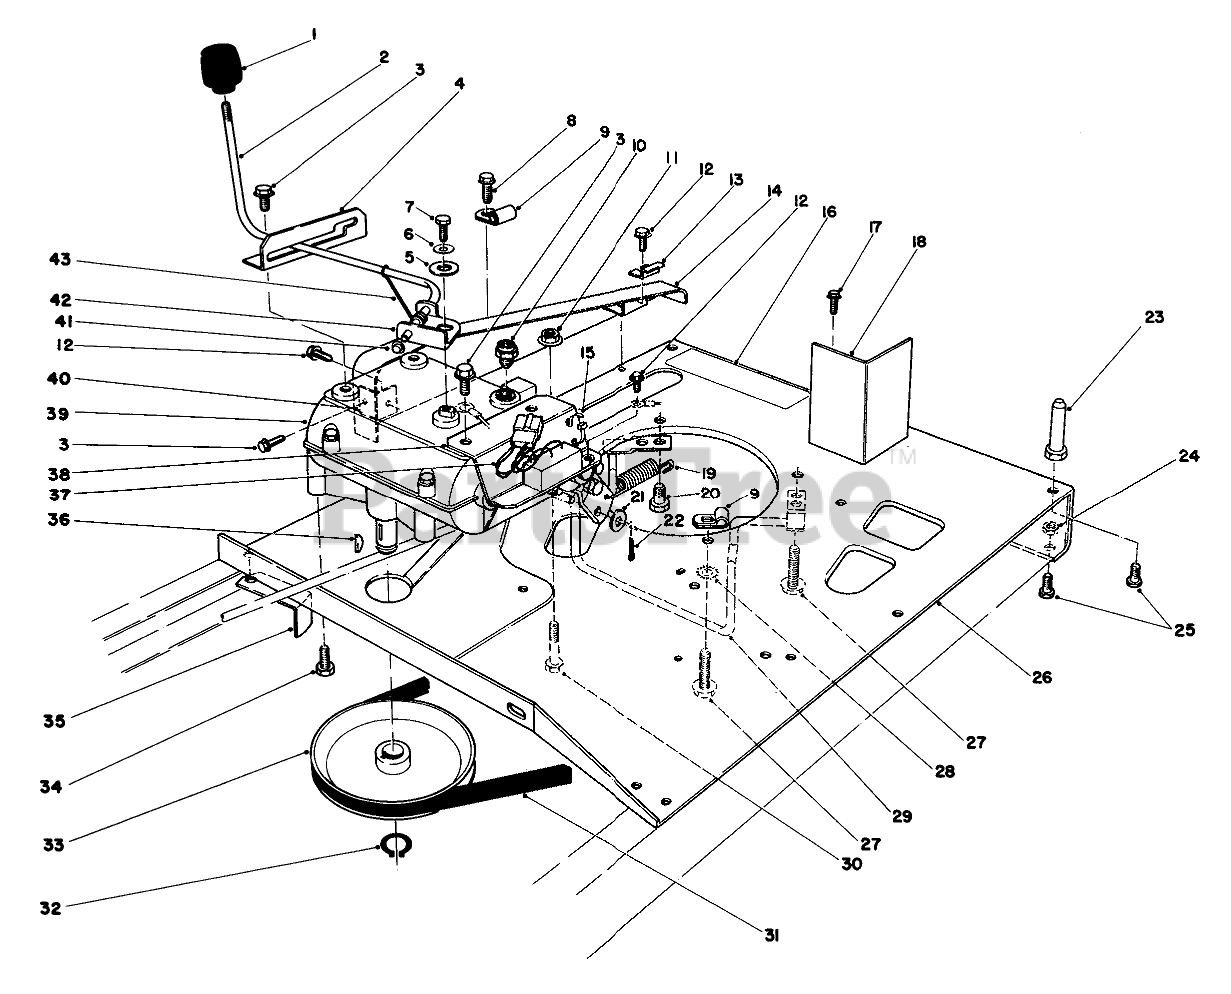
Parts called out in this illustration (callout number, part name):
2	SHIFT LEVER
3	SCREW-HWHTF
4	SHIFT LEVER GATE
5	WASHER-FLAT
6	WASHER-BELLEVILLE
7	SCREW-HH
8	SCREW-HHFTF
9	CLIP-FUEL LINE
10	NEUTRAL SWITCH
11	NUT-HF
12	SCREW
13	Clamp-Cable
14	Chain Guard
15	TIE-CABLE
16	Decal
18	Baffle-Carb
19	SPRING-RETURN, BRAKE
20	Screw-HH
21	WASHER-FLAT
22	PIN-COTTER
23	PIN-MOUNTING, LOWER
24	NUT-LOCK, CONE
25	SCREW-HH
26	Plate-Engine
27	SCREW-HWHTF
28	WASHER-LOCK
29	Belt Guide
30	SCREW-HH
31	V-BELT
32	RING-SNAP, EXTERNAL
33	PULLEY
34	5/16-18 X 5/8 SEMS SC
35	TRANS BELT RET B
36	KEY-WOODRUFF
37	Control Module
38	Mount Module
39	TRANSMISSION
40	CHAIN GUARD BRKT B
41	RETAINER-PUSH ON
42	SHIFT LEVER CLAMP
43	Spring-Shift Rod
